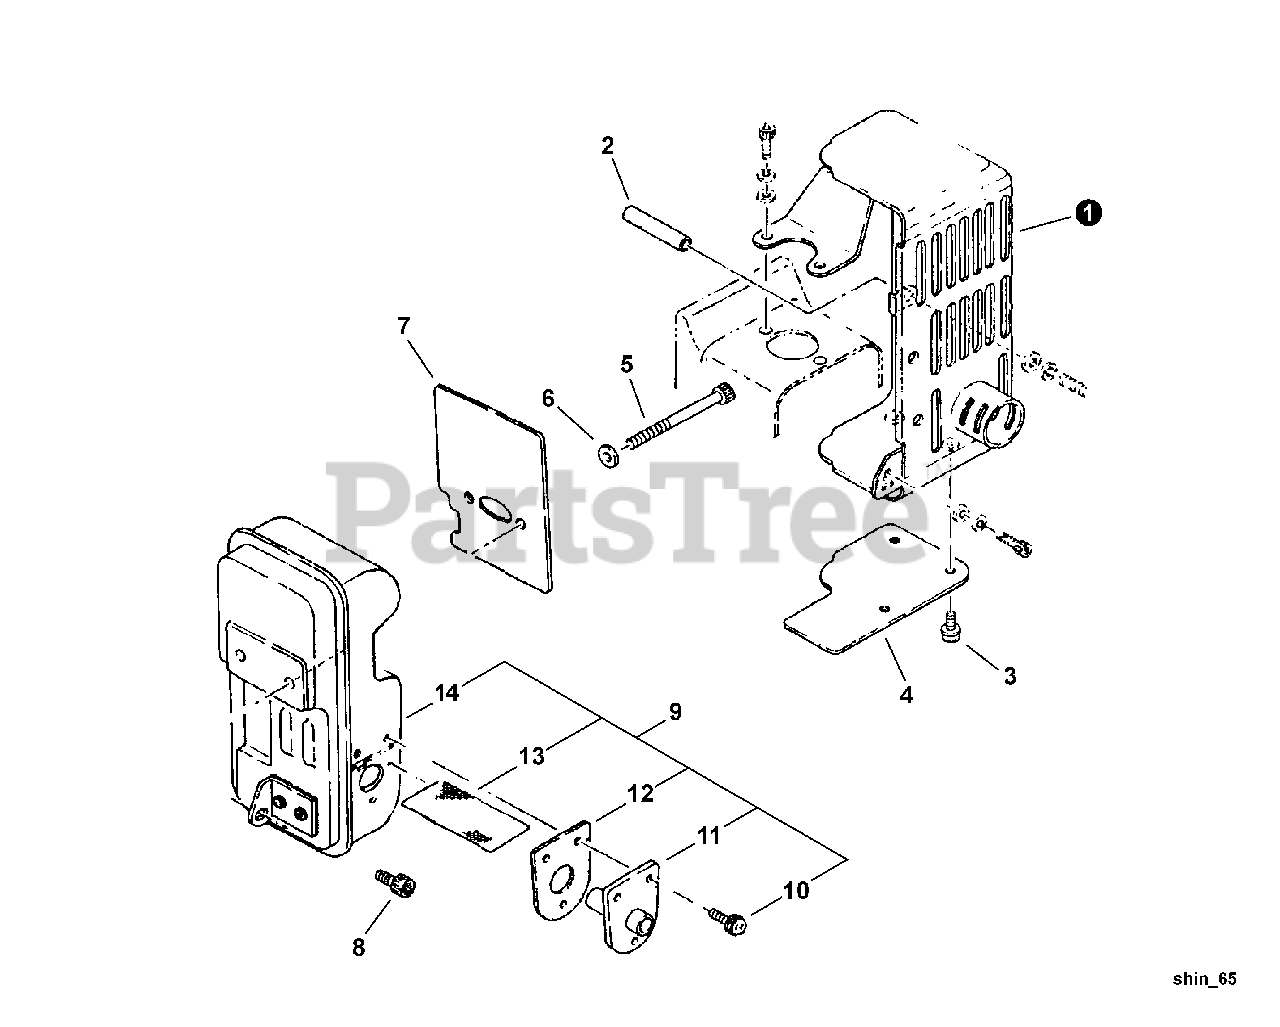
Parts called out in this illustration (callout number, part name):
1	COVER, EXHAUST
2	SPACER
3	SCREW - 4X8
4	GASKET
5	SCREW - 6X70
6	WASHER - 6
7	GASKET, EXHAUST
8	SCREW - 5X12
9	MUFFLER ASSY
10	SCREW - 4X12
11	GUIDE, EXHAUST
12	GASKET, EXHAUST
13	SCREEN, SPARK ARRESTOR
14	MUFFLER
